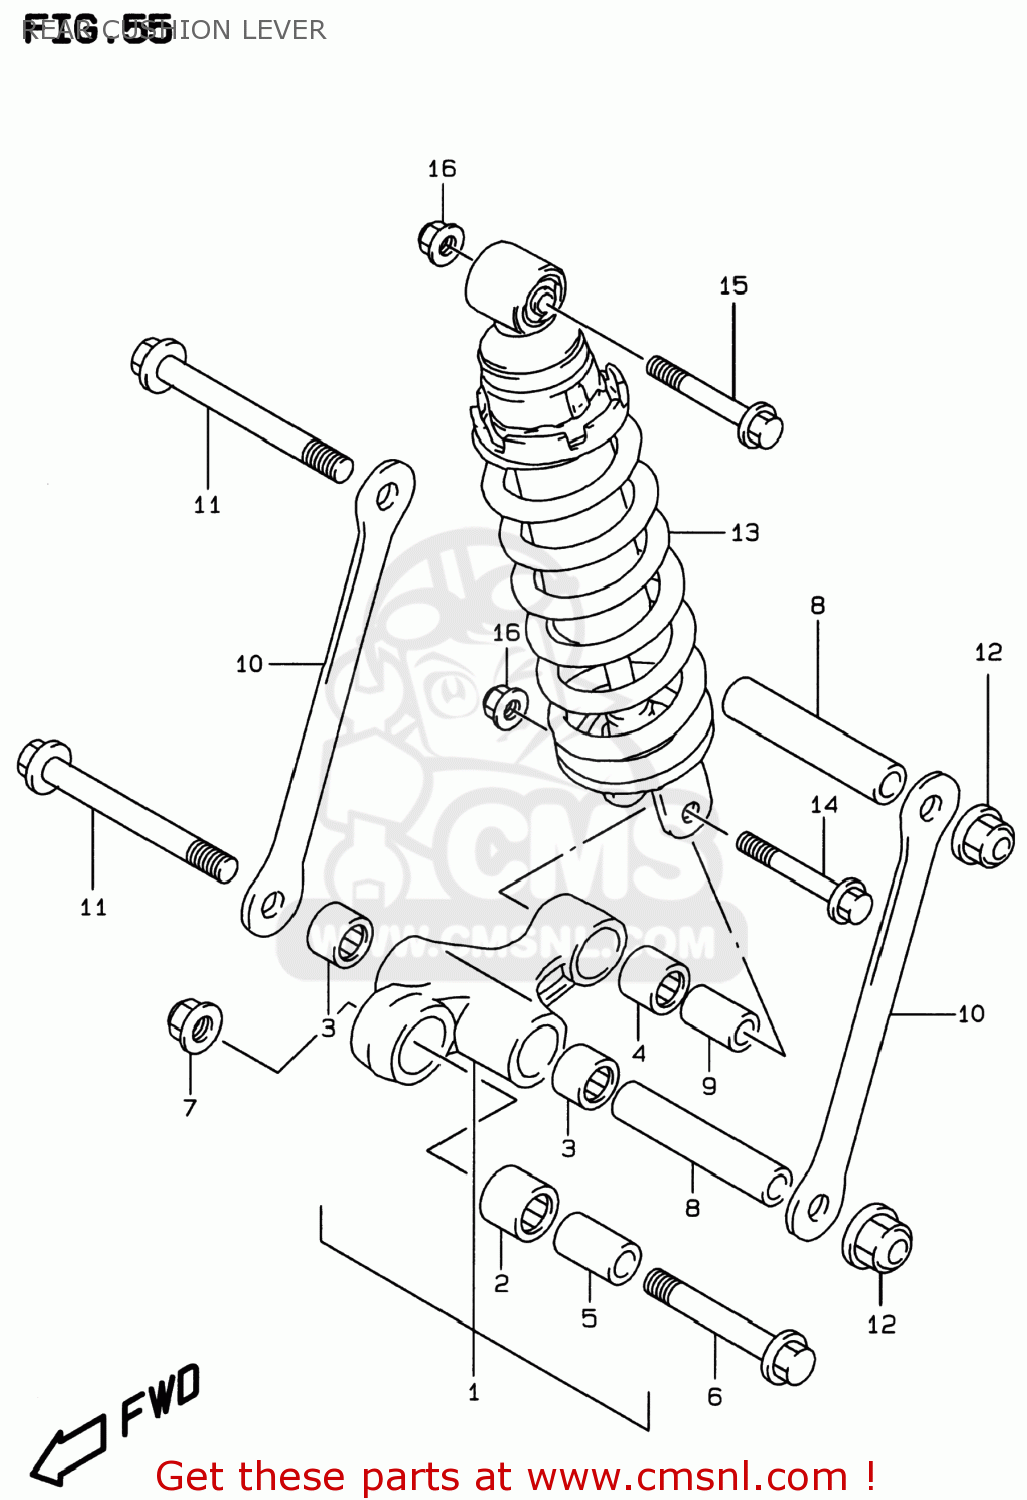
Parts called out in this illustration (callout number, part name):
1	LEVER SET,RR CUSHION
2	BEARING(20X27X26)
3	BEARING(17X24X25)
4	BEARING(17X24X26)
5	SPACER,RR CUSHION LEVER FR
6	BOLT,CUSHION LEVER FR
7	NUT 12MM
8	SPACER(12X17X85)
9	SPACER,RR CUSHION LEVER
10	ROD,RR CUSHION
11	BOLT(12X115)
12	NUT 12MM
13	ABSORBER ASSY,RR SHOCK
14	BOLT(10X54)
15	BOLT(10X50)
16	NUT
